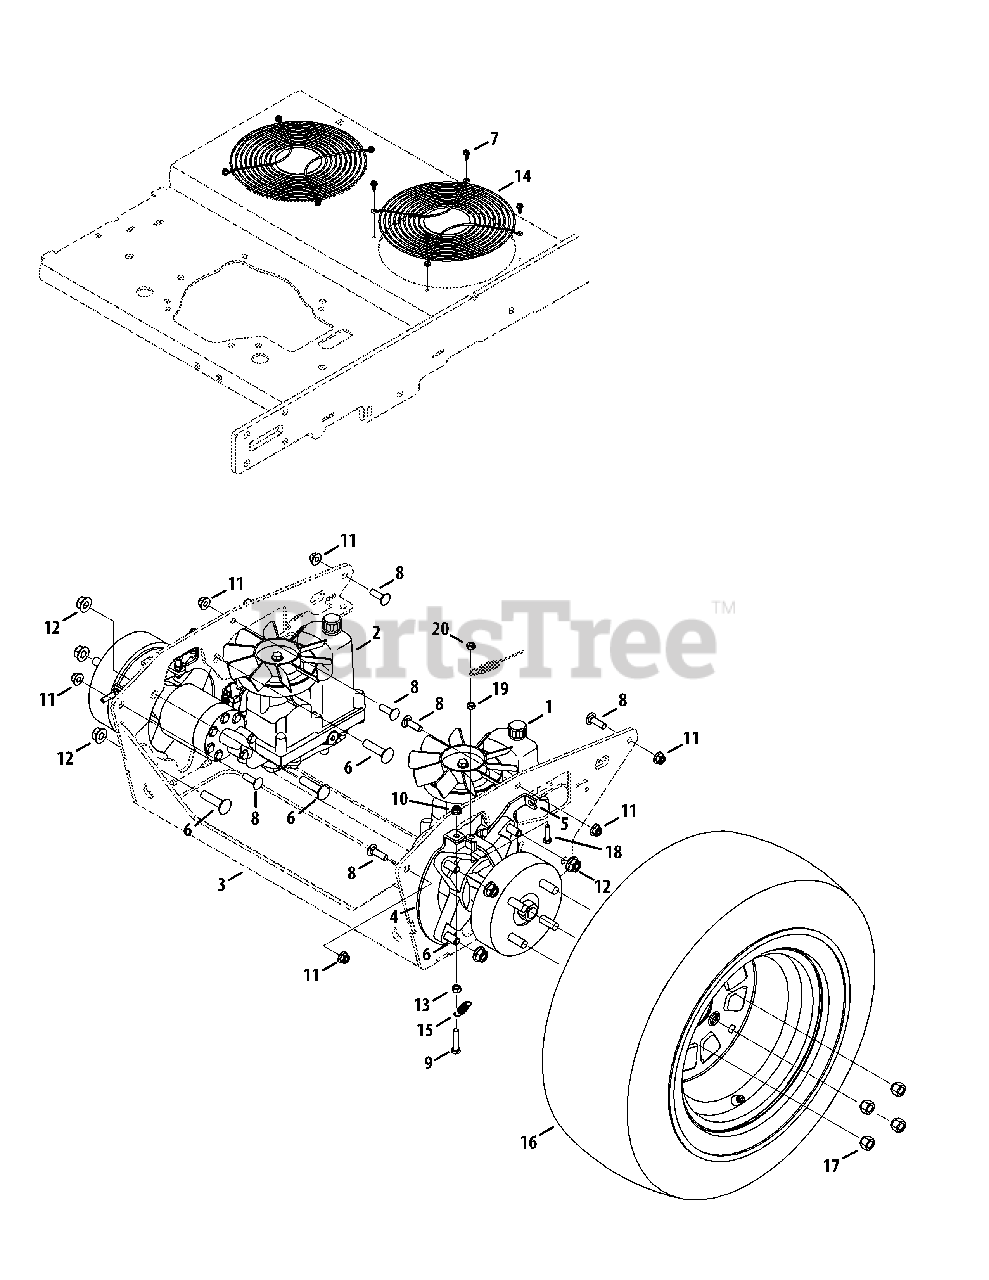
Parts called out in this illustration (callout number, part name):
1	Transmission, RH
2	Transmission, LH
3	Transmission Bracket Assembly
4	Spring Brake Mounting Bracket
5	Brake Cable Mounting Bracket
6	Carriage Bolt, 1/2-13 x 2.00
7	Screw, 10-24 x .500
8	Carriage Bolt, 3/8-16 x 1.25
9	Hex Cap Screw, 5/16-18 x 1.50
10	Nut, 5/16-18, Flangelock
11	Nut, 3/8-16, Flangelock
12	Nut, 1/2-13, Flangelock
13	Nut, 5/16-18, Hex
15	Extension Spring, .50 OD x 1.71
16	Wheel Assembly, 24 x 9.5-12
17	Lug Nut, 1/2-13
18	Hex Cap Screw, 5/16-18 x 1.00
19	Jam Nut, 5/16-18
20	Hex Lock Nut, 5/16-18
